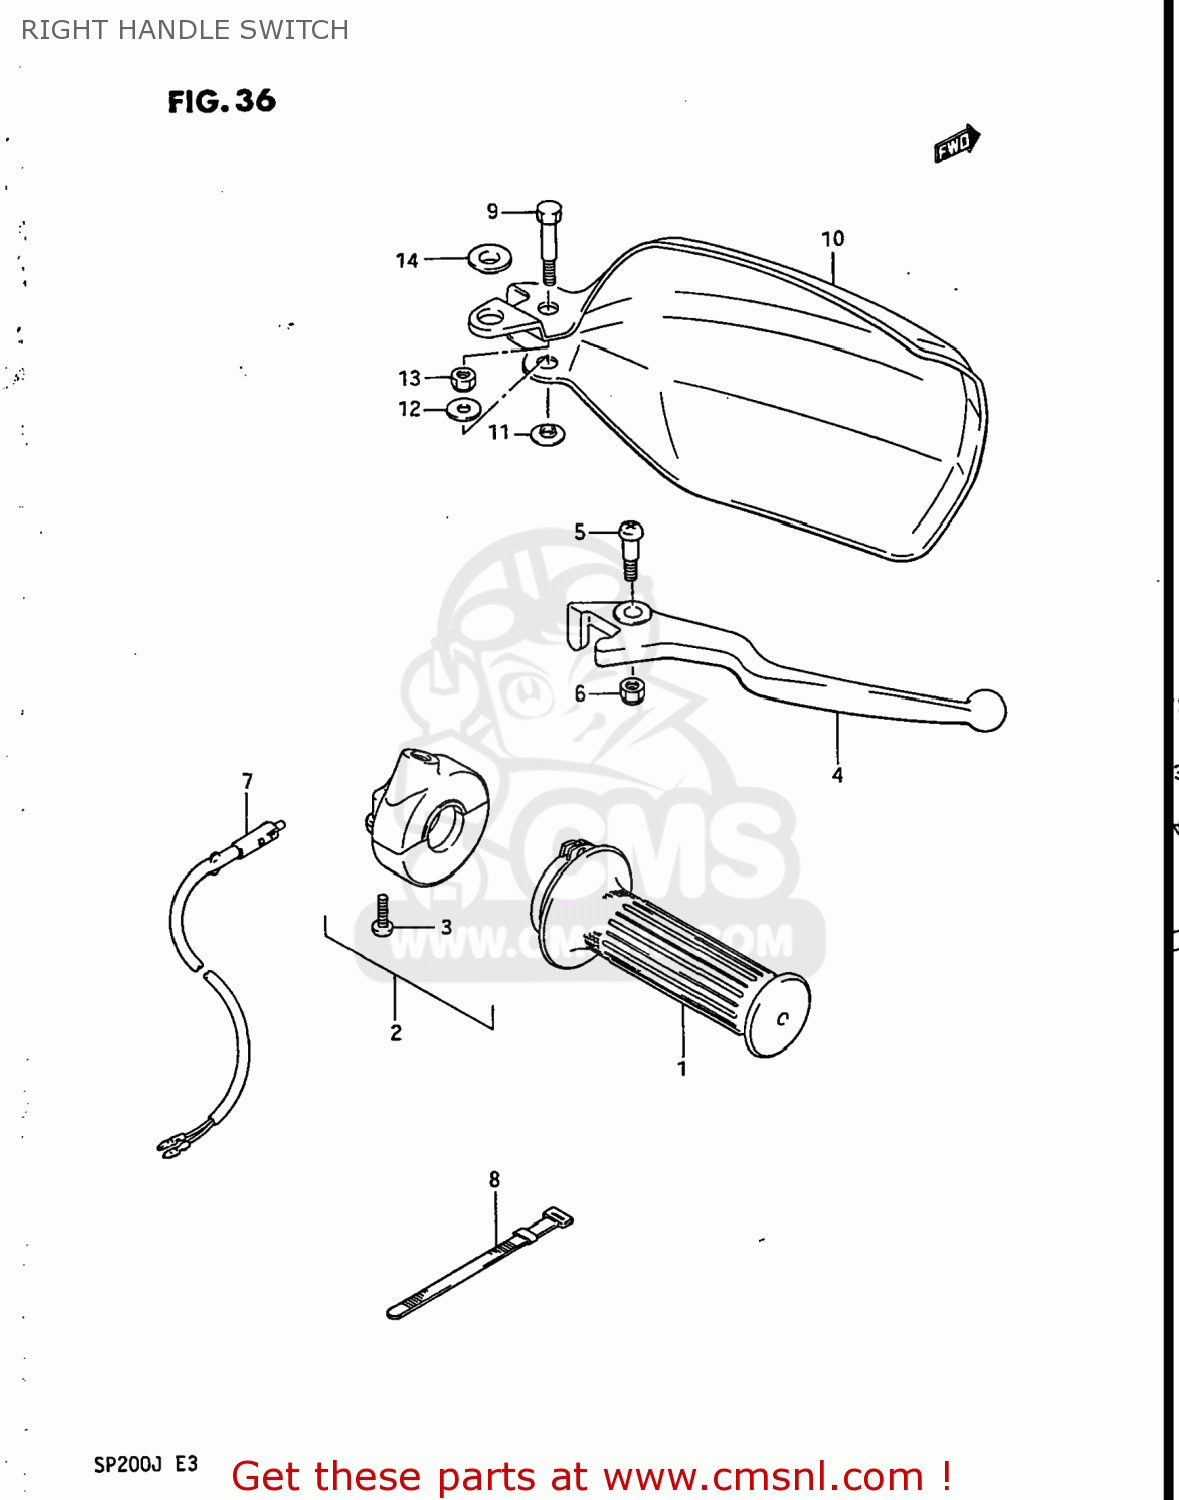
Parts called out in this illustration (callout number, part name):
1	GRIP,THROTTLE
2	CASE ASSY,THROTTLE
3	SCREW 5X20
4	LEVER,BRAKE
5	SCREW
6	NUT
7	SWITCH ASSEMBLY
8	CLAMP(L:120)
9	BOLT,LEVER PIVOT
10	COVER,KNUCKLE,RIGHT
11	WASHER
12	WASHER(6.5X16X1.2)
13	NUT 6MM
14	WASHER
